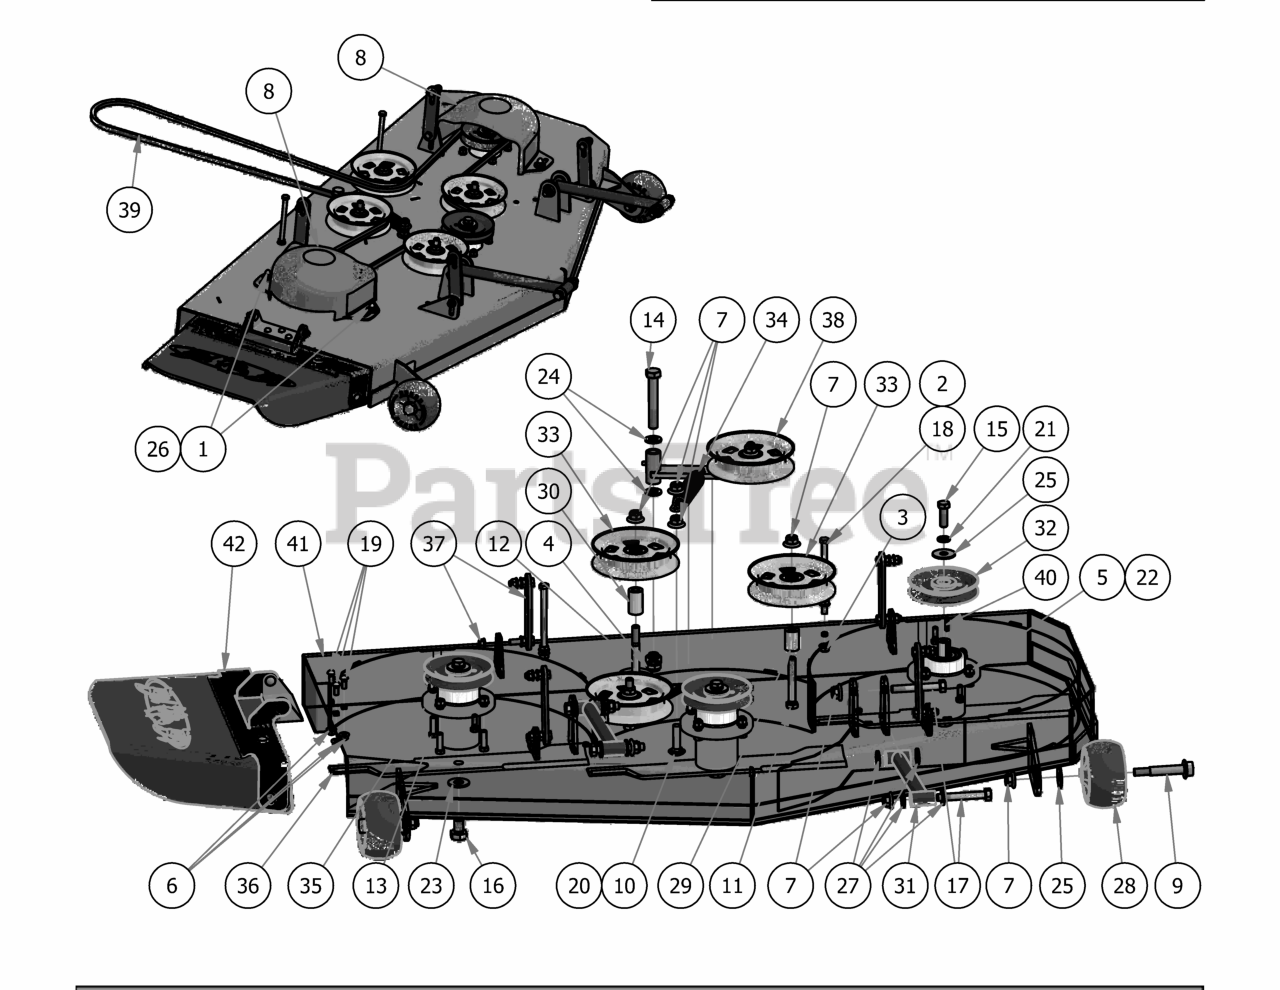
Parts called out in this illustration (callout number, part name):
1	Acorn nut-pulley Cover
2	3/8" Flange Nut
3	3/8" Nylock Flange Nut
4	5/8" Nylock (1/2 Jam)
5	3/8" Hex Nut
6	5/16" Nylon Flange Nut
7	1/2-13 Nylon Flange Nut
8	Pulley Cover
9	Deck Wheel Bolt
10	1/2 x 2" Carriage Bolt
11	1/2 x 3 1/2 Flange Bolt Grade 8
12	1/2" x 4" Bolt (Grade 8)
13	3/8" x 1 1/4" Hex Bolt
14	5/8" x 4" Hex Bolt
15	1/2"-20 x 1 1/2 - Grade 5 Fine Thread Bolt
16	5/8" x 1 1/2" Grade 8 Hex Bolt (Fine)
17	1/2-13 x 3 1/2 GR 5 Hex Bolt
18	3/8-16 x 5 1/2 Hex Bolt
19	5/16-18x3/4 carriage bolt
20	.517 Square Hole Round Washer
21	1/2" Lock Washer
22	3/8" Lock Washer
23	5/8'' Flat Washer
24	.630 ID Plastic Washer
25	1/2" Belleville Washer
26	.360 ID Plastic Washer-Black
27	.505 Nylon Spacer
28	Deck Wheel
29	Idler Pulley Standoff
30	1 3/4" Pulley Spacer
31	MZ/ZT Deck Locator
32	54 MZ Spindle Pulley
33	5-3/4 Idler Pulley
34	Deck Idler Spring
35	Spindle Assembly-MZ
36	54" MZ Fusion Blade
37	Deck Hanger Assembly
38	2017 54"/48" Deck Idler Assembly
39	B155.75 Deck Belt
40	3/16 x 1 Square Key
41	2017 MZ 54" Deck
42	MZ Discharge Chute Assembly
